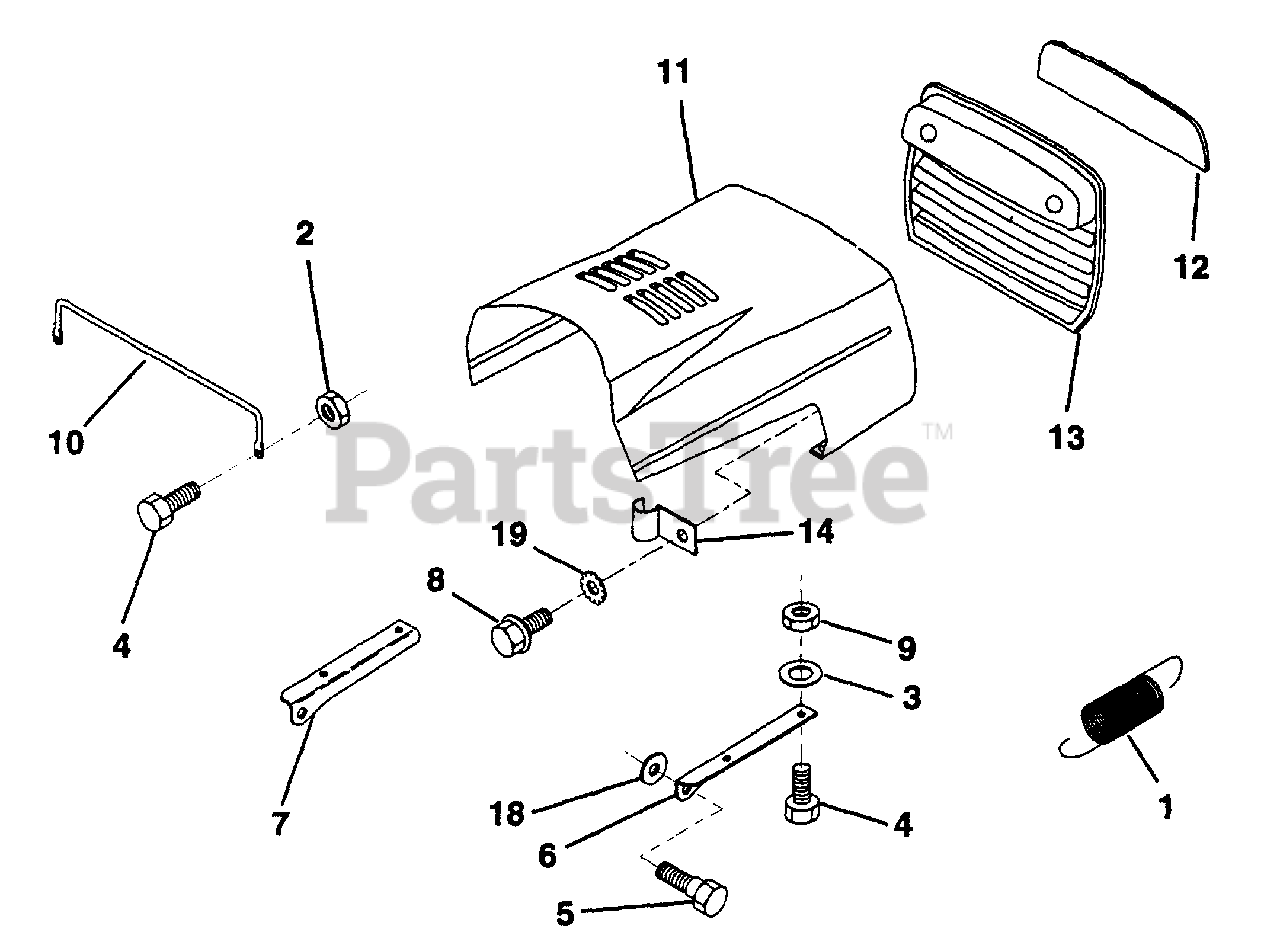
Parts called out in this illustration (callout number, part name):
1	Spring, Ext
2	Nut, Keps
3	Washer 9/32 x 7/8 x 16 Ga
4	Bolt, Fin Hex 1/4-20 x .75
5	Bolt, Shoulder 5/16-18 Thd Frmr
6	Bracket Hood RH
7	Bracket Hood LH
8	Screw, Sltd Hex Hd w/PI Washer
9	Nut, Lock w/Insert 1/4-20
10	Brace, Hood
11	Hood
12	Lens, Headlight Bar
14	Clip, Line Fuel
18	Washer 11/32 x 11/16 x 16 Ga
19	Washer Lock 1/4 Ext/Int Tooth
